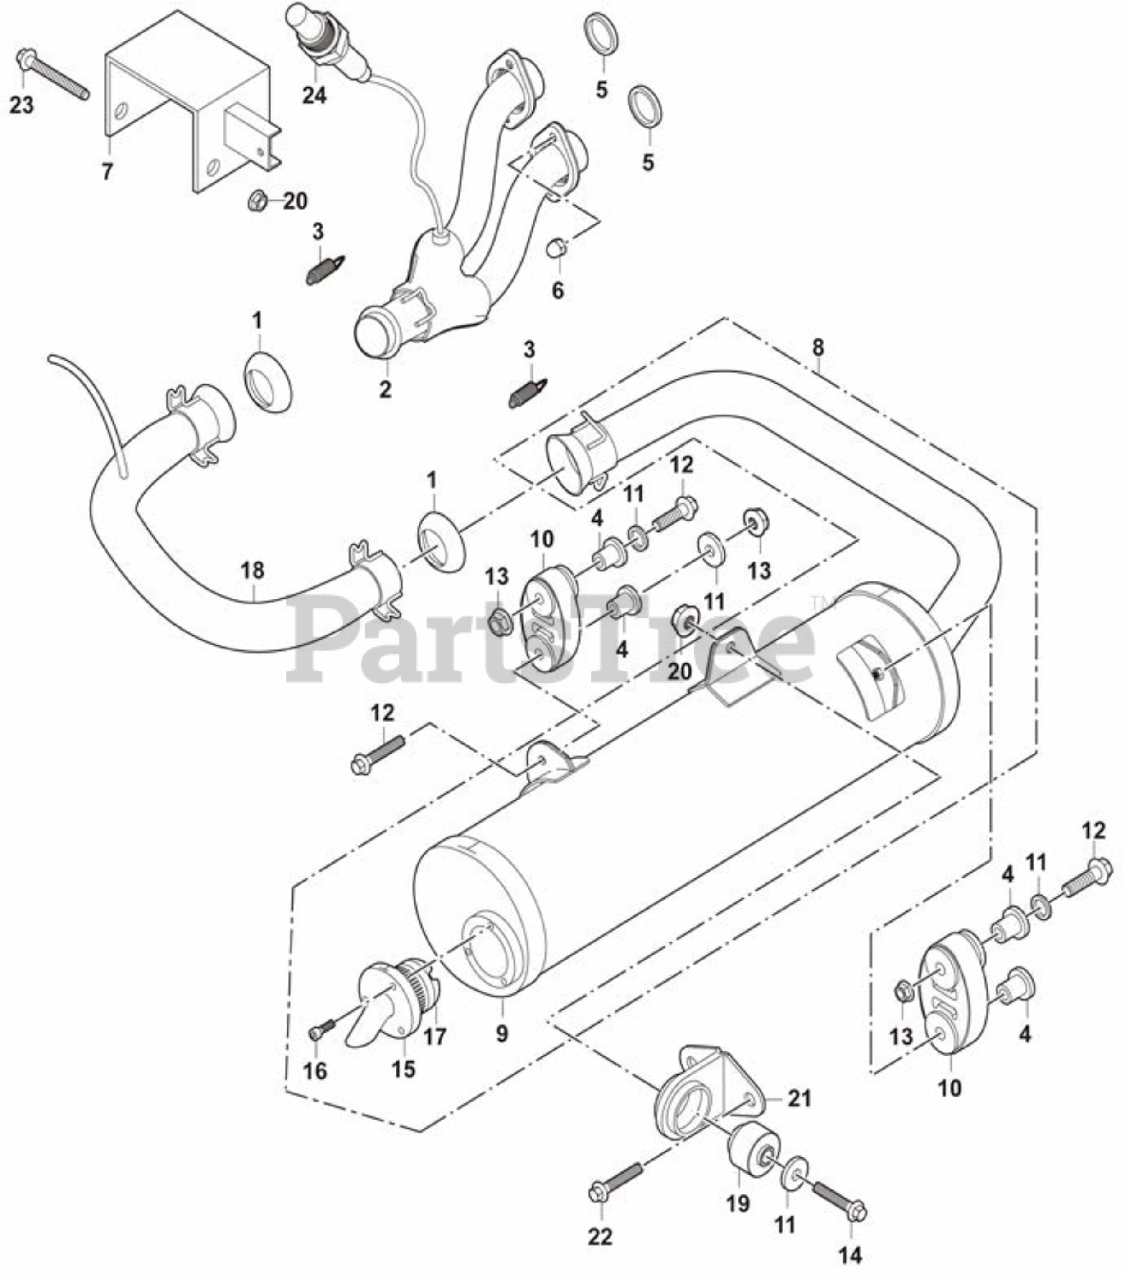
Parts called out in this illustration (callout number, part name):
1	sealing gasket,hemispherical 42
2	welding assembly ,exhaust pipe
3	Draw Spring A
4	Collar Bush6X10X22X17
5	seal ring,Exhaust Pipe 31X41X5.5
7	Suspension Assy I, Exhaust Pipe
8	Muffler Assy
9	Welding assembly,muffler
10	Damping Gasket Assy, Muffler
11	Heat insulation Gasket
12	Hexagon Flange BoltM6X30
13	Hexagon Flange Nut M6
14	Hexagon Flange BoltM8X45
15	Muffler Tail Decorative Cover
16	Socket Hexagon Head Screw M6X20
17	Flame Screen
18	Exhaust Pipe Shield II
19	Suspension Bushings
20	Hexagon Flange Bolt M8
21	Suspension Assy II, Exhaust Pipe
22	Hexagon Flange Bolt M8X16
23	Hexagon Flange Bolt M8X70
24	Oxygen sensor
